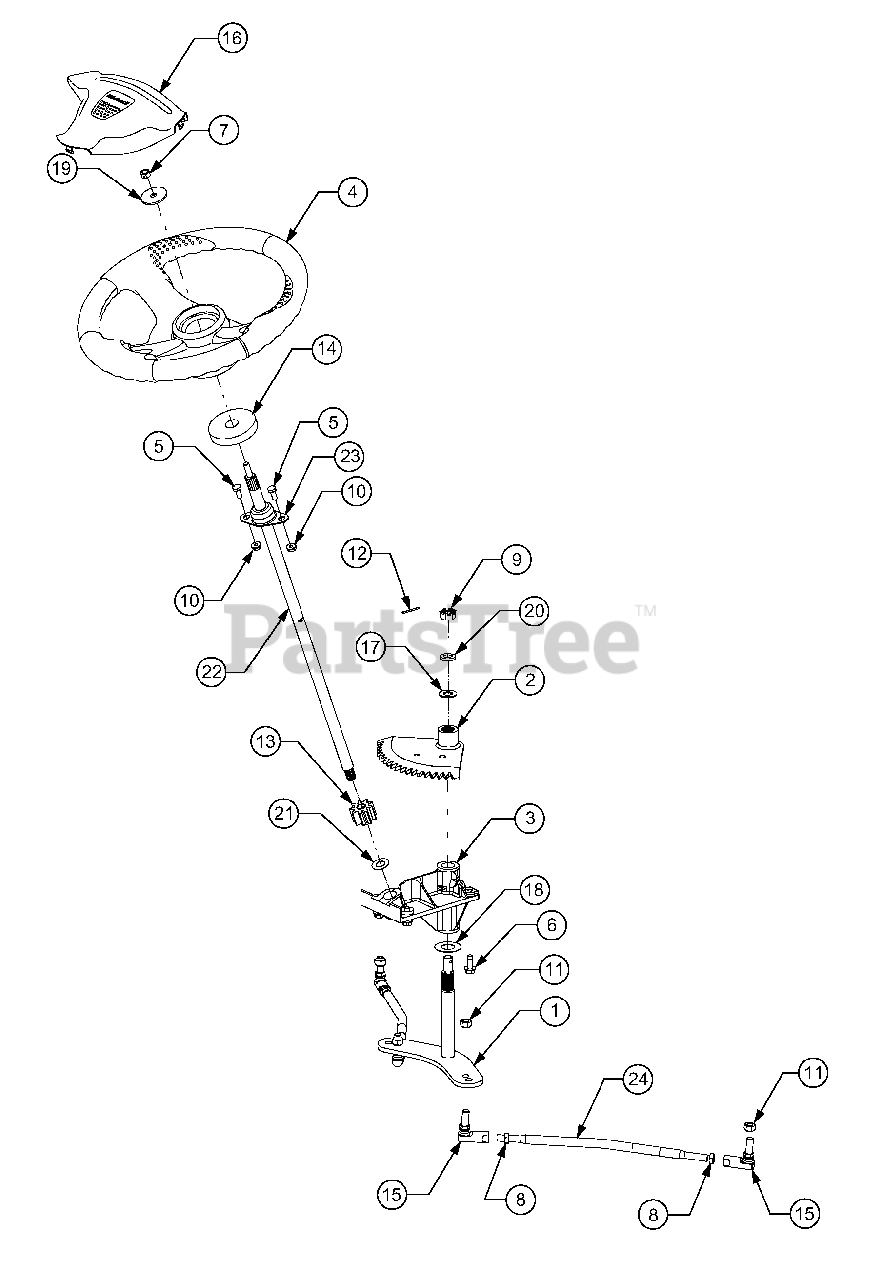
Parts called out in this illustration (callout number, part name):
1	Arm Assy, Lower Steering
2	Segment Assy, 18T Steering
3	Housing Assy,
4	Wheel, Steering, Soft Grip
5	Screw, Hex Cap, 5/16 - 18 x .75, GR5
6	Screw, Hex Wash. Hd. Tapp 5/16 - 18 x .75
7	Nut, Hex Center Lock, 5/16-18
8	Nut, Hex Jam, 3/8-24 GR2
9	Nut, Hex Slotted, 1/2-20 GR5
10	Nut, Hex Flange Lock, 5/16 - 18
11	Nut, Hex Lock, 3/8-24 GR5
12	Pin, Cotter, 3/32 Dia x 1.25
13	Pinion, Steering
14	Gasket, Steering
15	Joint, Ball, 3/8-24
16	Cover, Steering Wheel
17	Washer, Flat, .510 x 1 x .06 Thk
18	Washer, Flat, .760 x 1.5 x .03 Thk
19	Washer, Bell
20	Washer, Lock, 1/2
21	Washer, Flat, .531 x 1 x .027 Thk
22	Shaft, Steering
23	Bearing, Flange
